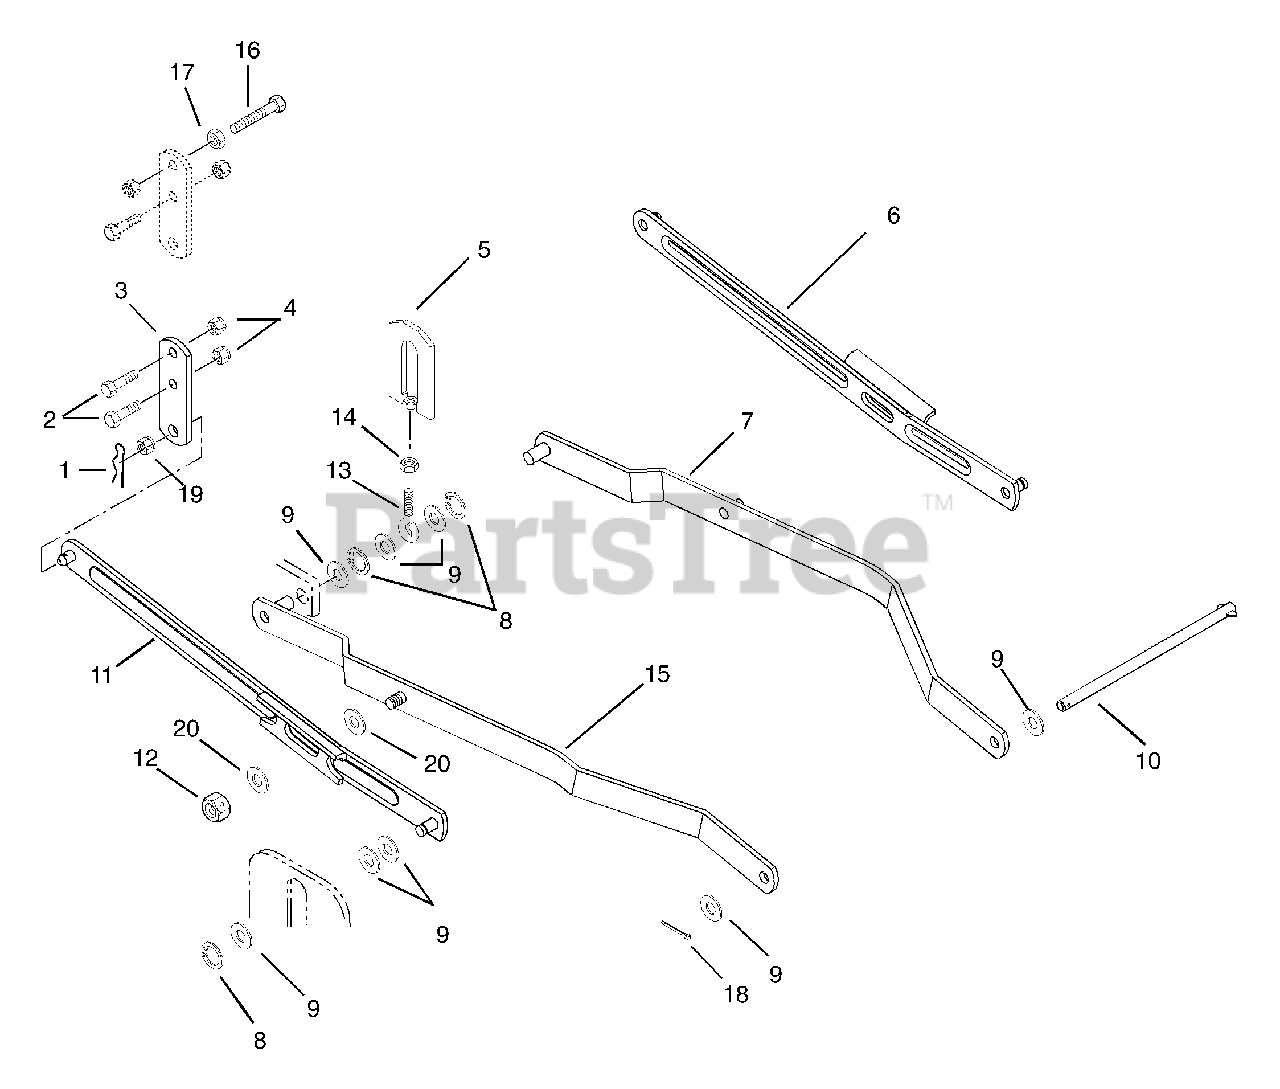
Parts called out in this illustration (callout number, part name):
1	PIN-HAIR-EXT .12X.31X2.37 YWZC
2	@BLT-HEX .38-16X.75 GR5 YWZC
3	HANGER BRACKET
4	@NUT-LK-CTR .38-16 YWZC
5	LINK, ADJUSTMENT
6	REAR HANGER - LH
7	L.H. LIFT ARM
8	RG-RTNG-EXT .500X.050 (SNAP)
9	@WSHR-FL-STL.531X1.06X.095YWZC
11	REAR HANGER - RH
12	@NUT-LK-CTR .62-11 YWZC
14	NUT-HEX-JAM .375-16 YWZC
15	R.H. LIFT ARM
16	@BLT-HEX .38-16X1.75 GR5 YWZC
17	@NUT-HEX .38-16 YWZC
18	@PIN-CTR .12X1.00 EXTPRSQCT YZ
19	WSHR-FL-STL .630X1.005X.062 YZ
20	@WSHR-FL-STL.656X1.31X.095 YWZ
